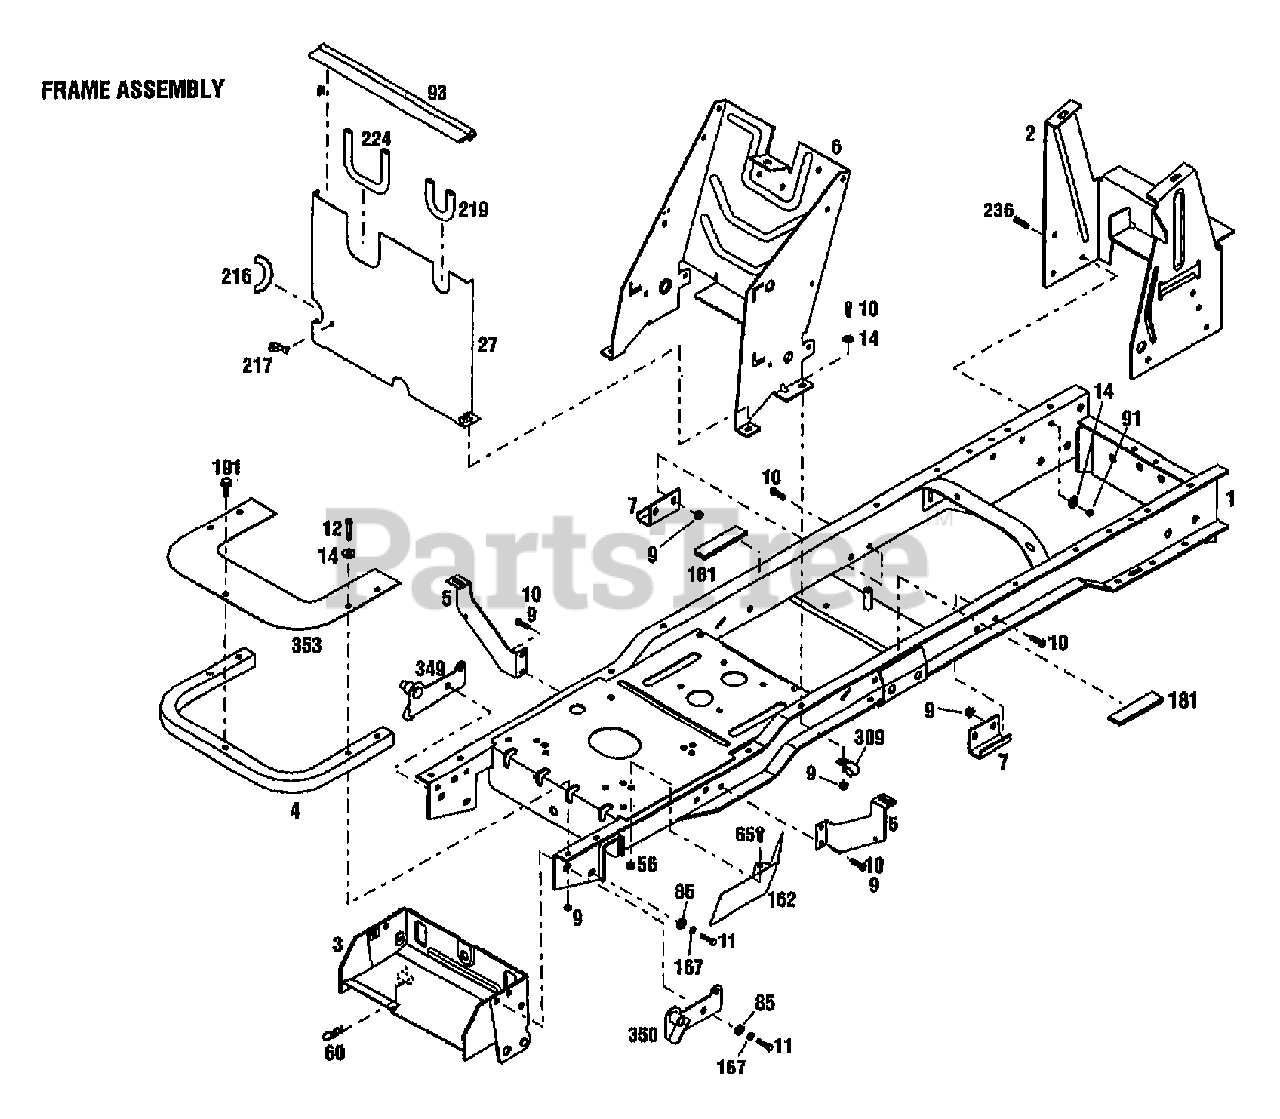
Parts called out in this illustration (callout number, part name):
1	ASSM-FRAME LTX {13096/097}
1	ASSM-FRAME {13099}
2	SUPPORT-REAR TANK
3	ASSM-BRKT ATTACHMENT
4	BUMPER-FRONT
5	SUPPORT-FENDER
6	SUPPORT-CONSOLE
7	STOP-MOWER DECK
9	NUT-HFLK 5/16-18 ZP
10	SCR-HHC 5/16-18X.75 GR 5 ZP
11	SCR-HH 3/8-16X1.0 G5 ZP
12	SCR-HH 5/16-18X1.75
14	WASHER-FLAT 5/16 SAE
27	SHIELD-HEAT {13099}
56	NUT-HF/LK 1/4-20 ZP
60	PIN-HITCH .125X2.56 ZP
65	SCR-HH 1/4-20X.625
85	WASHER-FLAT 3/8 SAE
91	NUT-TOP/LK 5/16-18 ZP
93	GASKET-HEAT SHIELD {13099}
162	SHIELD-HEAT UPPER {13099}
167	WASHER-LK .375 @ DEPL
191	SCR-FLANGE 1/4-20X3/4 GR5
216	TRIM {13099}
217	HANGER-CABLE {13099}
219	TRIM {13099}
224	TRIM-HEAT SHIELD {13099}
236	SCR-HFLK 5/16-18X.75 ZP
309	CLIP-J
349	PLATE-PIVOT RH
350	PLATE-PIVOT LH
353	SHIELD-HEAT {13099}
